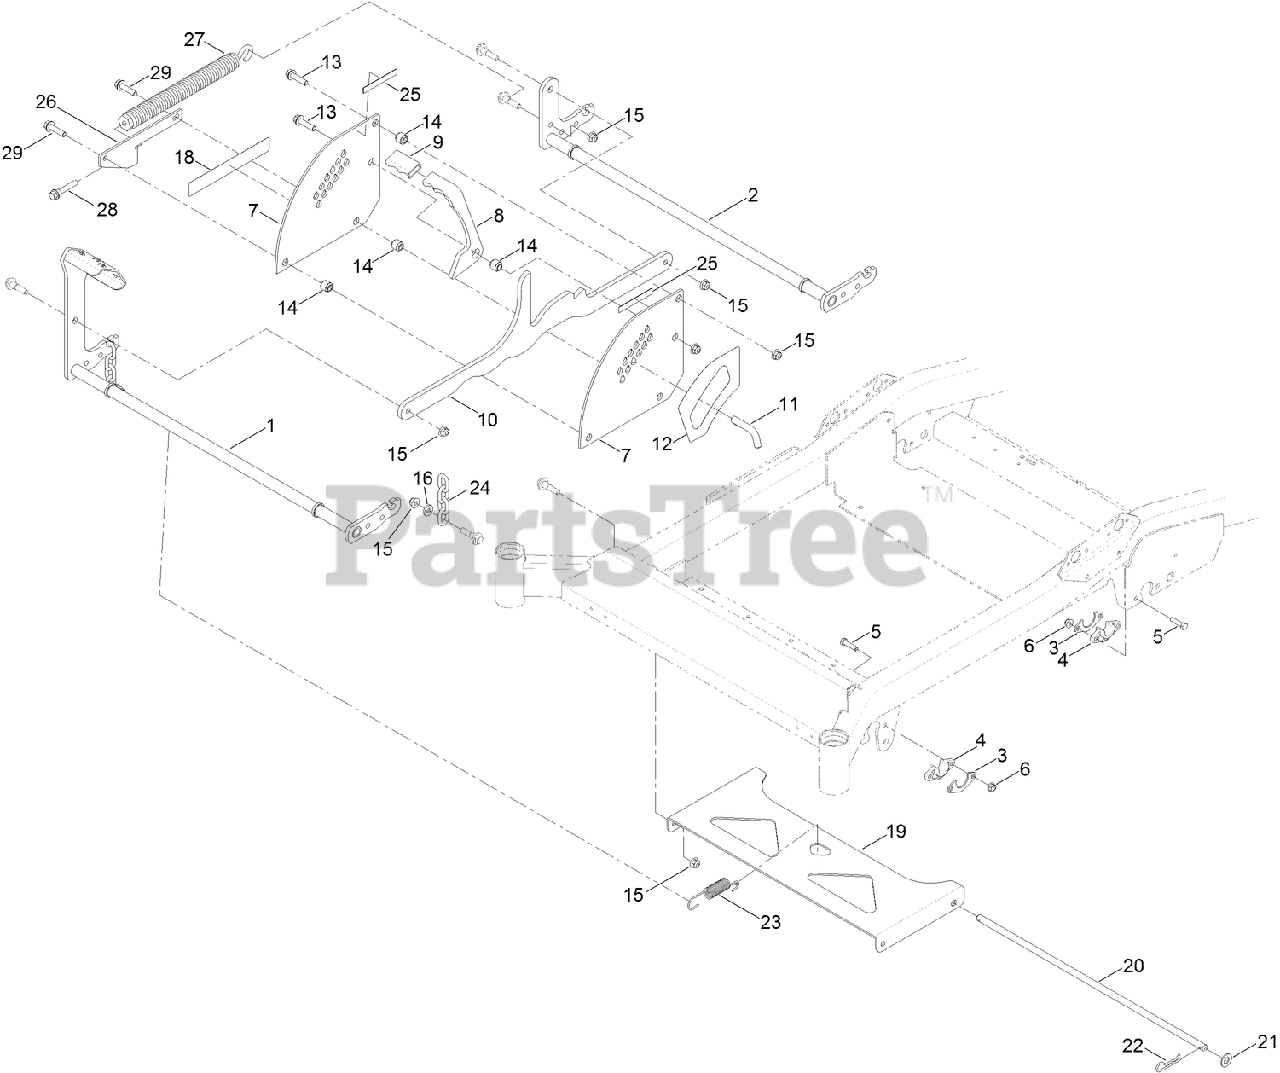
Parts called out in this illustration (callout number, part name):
1	PIVOT-FRONT
2	PIVOT-REAR
3	GUSSET-LIFT, DECK
4	BUSHING-FLANGE
5	SCREW-HH
6	NUT-HF, NI
7	PLATE-DECK, LIFT
8	LOCK-TRANSPORT, HOC
9	GRIP-FLAT
10	LINK-HOC
11	PIN-HOC
12	DECAL-HOC
13	SCREW-HHF
14	SPACER-STEP, DOUBLE
15	NUT-HF, NI
16	SPACER
19	PAN-DECK, PIVOT
20	ROD-DECK, PIVOT
21	WASHER-FLAT
22	PIN-COTTER
23	SPRING-EXTENSION
24	CHAIN-DECKLIFT
25	PAD-RUBBER
26	SUPPORT-SPRING
27	SPRING-EXTENSION
28	BOLT-SHOULDER
29	SCREW-HHF
